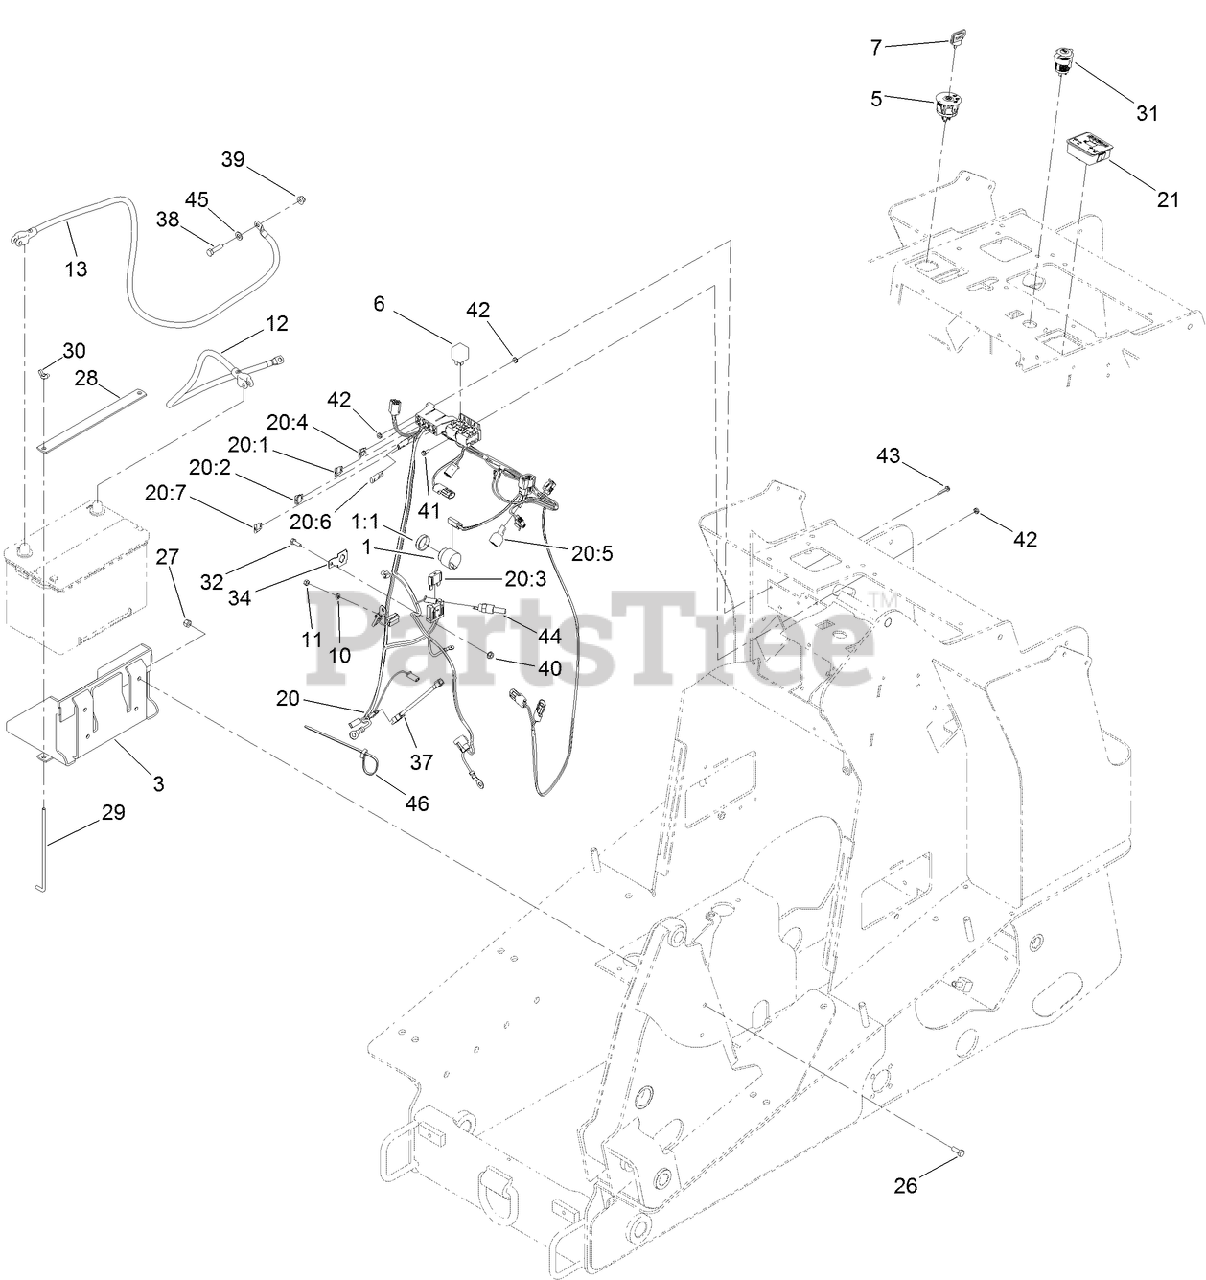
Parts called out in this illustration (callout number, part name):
1	AUDIO ALARM ASM
1:1	NUT-PLASTIC, KNURLED
3	TRAY-BATTERY
5	SWITCH-IGNITION
7	KEY-IGNITION
10	WASHER-LOCK, SPRING
11	NUT-HEX
12	CABLE-BATTERY, POSITIVE
13	CABLE-NEGATIVE
20	HARNESS-WIRE
20:1	FUSE-BLADE, 10 AMP
20:2	FUSE-BLADE, 15 AMP
20:3	FUSE-BLADE, 50 AMP
20:4	FUSE-BLADE, 7.5 AMP
20:6	CAP-PLUG
20:7	FUSE-BLADE, 20 AMP
21	MODULE-HOUR METER
26	SCREW-HH
27	NUT-LOCK, NI
28	STRAP-HOLD DOWN, BATTERY
29	ROD-HOLD DOWN, BATTERY
30	Wingnut
31	RECEPTACLE-12V
32	SCREW-HH
34	CLIP-FUSE
37	HARNESS-LINK, FUSIBLE
38	SCREW-HH
39	NUT-HF, NI
40	NUT-HF
41	SCREW-HWH
42	NUT-KEPS
43	SCREW-HWHTF
44	SWITCH-TEMP
45	WASHER-PLAIN
46	TIE-CABLE
